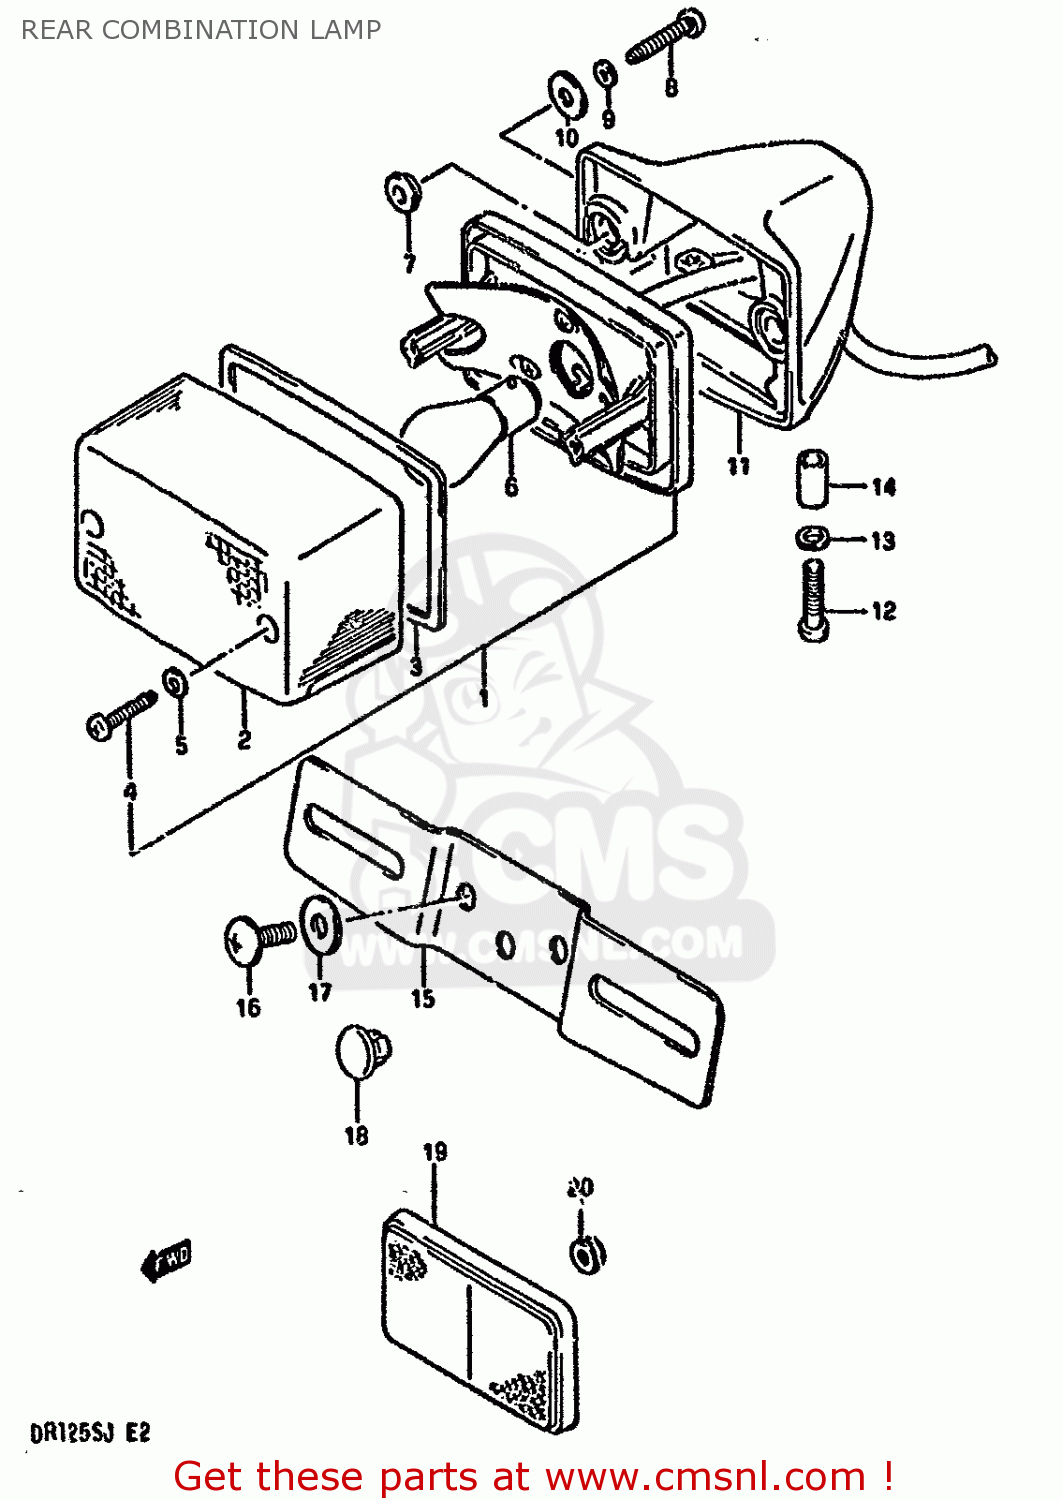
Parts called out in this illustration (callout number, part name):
1	LAMP UNIT,REAR COMBINATION
2	LENS
3	GASKET,RR COMBI LAMP LENS (NAS)
4	SCREW
5	GASKET (NAS)
6	BULB(6V,21/5W)
7	SPACER,RR COMBI
8	SCREW
9	WASHER,LOCK
10	WASHER
11	BRACKET UNIT,TAIL LAMP
12	SCREW
13	WASHER,LOCK
14	SPACER(6.4X9.2X12)
15	PLATE,RR LICENSE
16	SCREW
17	WASHER
18	CUSHION
19	RR ASSY,RR
20	NUT
